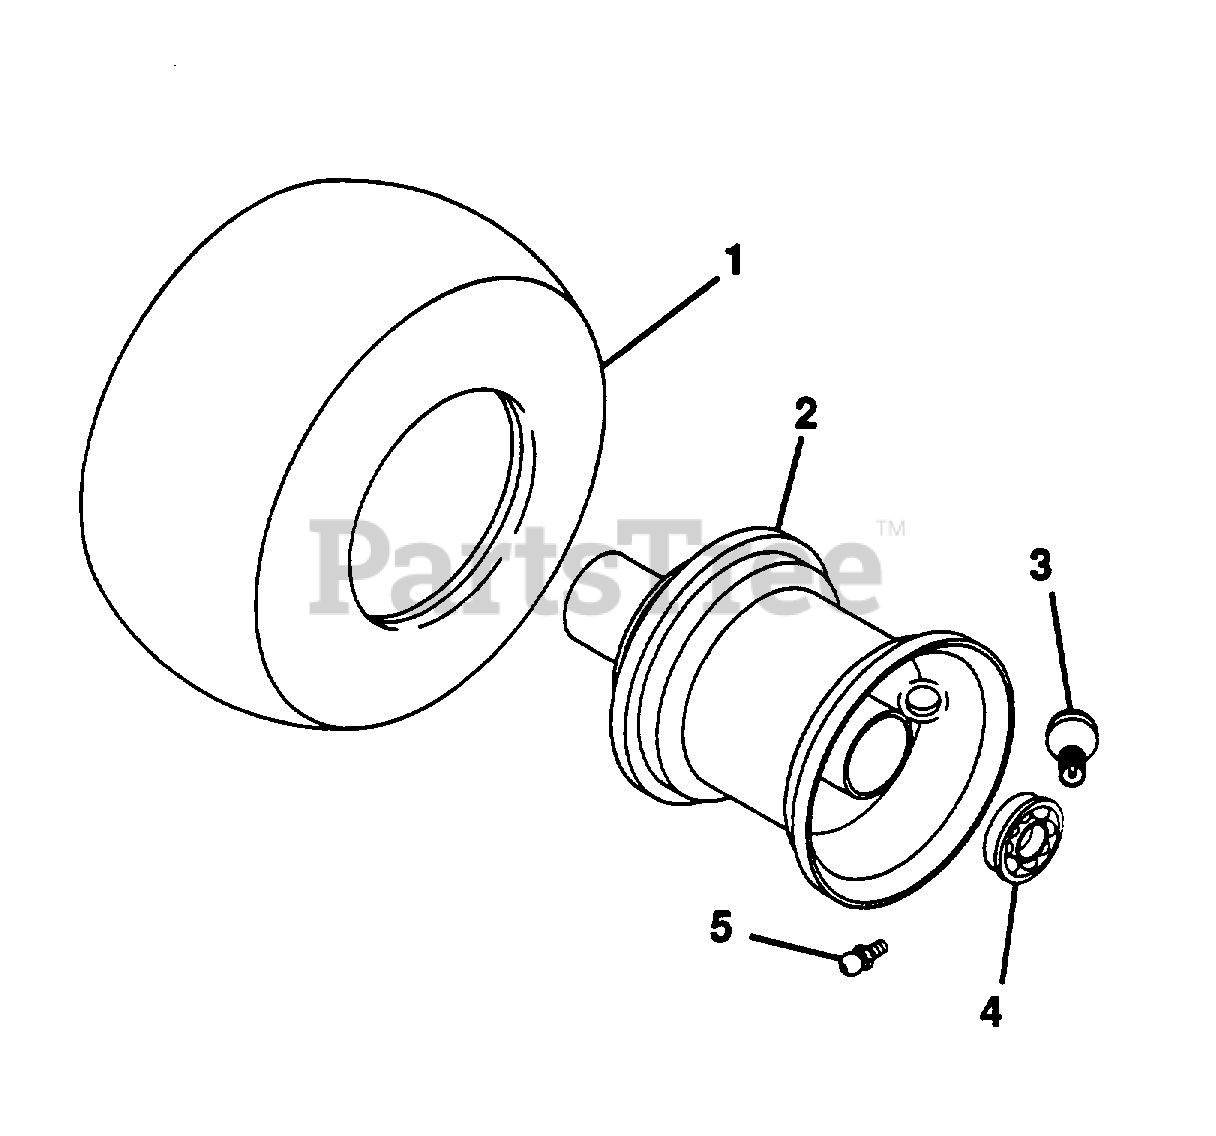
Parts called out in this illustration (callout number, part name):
1	TIRE, 13X6.50-6
2	ASSEMBLY, RIM
3	ASSEMBLY, VALVE STEM
4	BEARING, BALL
5	FITTING, LUBE 1/4-28
